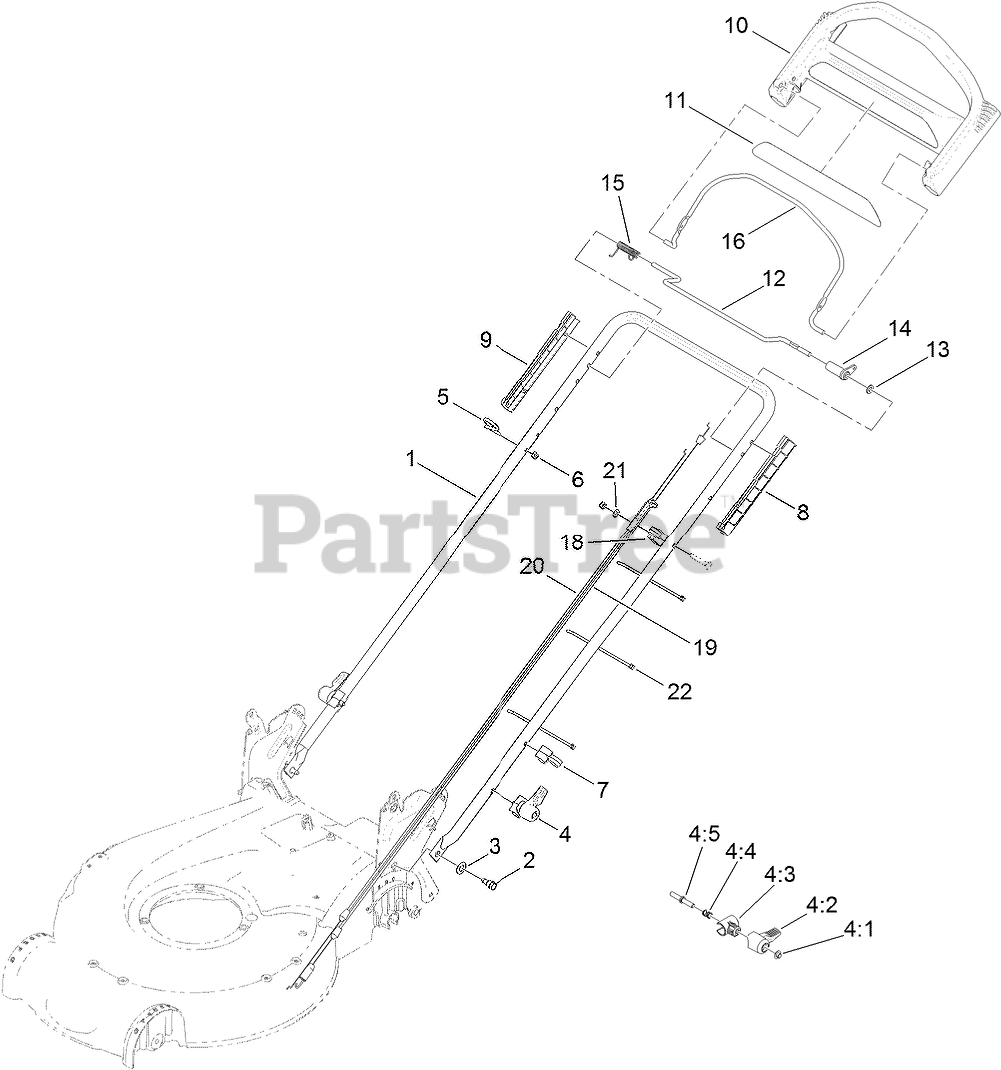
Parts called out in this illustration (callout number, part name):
2	BOLT-SHOULDER
3	WASHER-SPRING, CONICAL
4	QUICK RELEASE ASM
4:1	NUT-PUSH
4:2	LEVER
4:3	ANCHOR-SPRING
4:4	SPRING-COMPRESSION
4:5	ROD-RELEASE
5	GUIDE-ROPE
6	NUT-LOCK, NI
7	GUIDE-CABLE
8	GUIDE-LH
9	GUIDE-RH
10	HANDLE-CONTROL
11	DECAL-HANDLE
12	BAR-CONTROL, TRACTION
13	WASHER-PLAIN
14	LEVER-TRACTION
15	Spring-Torsion
16	Bail-Brake
18	ANCHOR-CABLE
19	CABLE-TRACTION
20	CABLE-BRAKE
21	WASHER-FLAT
22	TIE-CABLE
